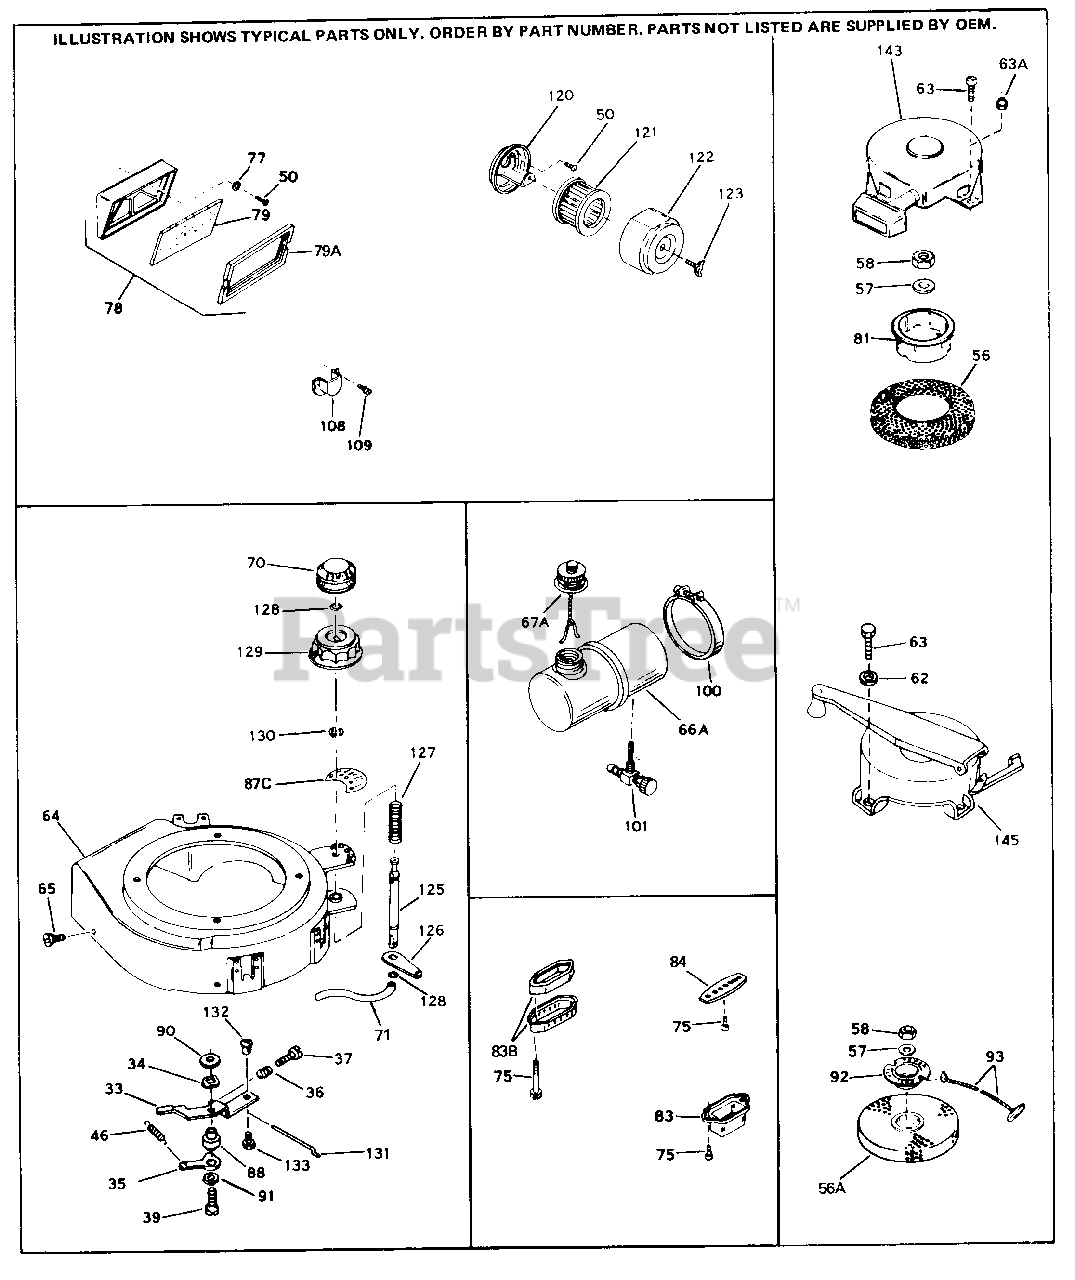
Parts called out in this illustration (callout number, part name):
33	Lever, Control
35	Lever, Adjusting
37	Screw, 5-40 x 7/16"
39	Screw, Torx T-25, 10-24 x 7/8
46	Spring, Governor
50	Screw, 10-32 x 5/8"
56	Screen, Air
57	Washer, Lock
58	Nut, Flywheel
63	Pop Rivet (3/16" dia.) (Buy locally) As req.
63	Screw, 1/4-28 x 3/8" Use as required
64	Blower Housing On some late productio n models, the top mounted rewind star ter is riveted to the blower housing. If either the starter or blower hou sing needs replacement, the other may need the holes used for pop riveting enlarged to accomodate us
65	Screw, 1/4-20 x 3/8"
75	Screw, 1/4-20 x 1-7/8"
77	Washer, Flat #10
81	Cup, Starter
83	Muffler
87C	Decal, Dial control
120	Base Assy., Filter
121	Air Filter
122	Cover, Air filter
123	Screw, 10-24 x 1/2"
125	Shaft, Dial control
126	Lever, Dial control
127	Spring, Dial control
128	Ring, Retainer
129	Knob, Dial control
130	Ring, Retainer
131	Link, Dial control
132	Swivel, Dial control
133	Screw, 6-32 x 3/8"
143	Rewind Starter NOTE: On some late pr oduction models, the top mounted rewi nd starter is riveted to the blower h ousing. If the starter or blower hou sing needs replacement, the other may need the holes used for pop riveting enlarged to use standar
